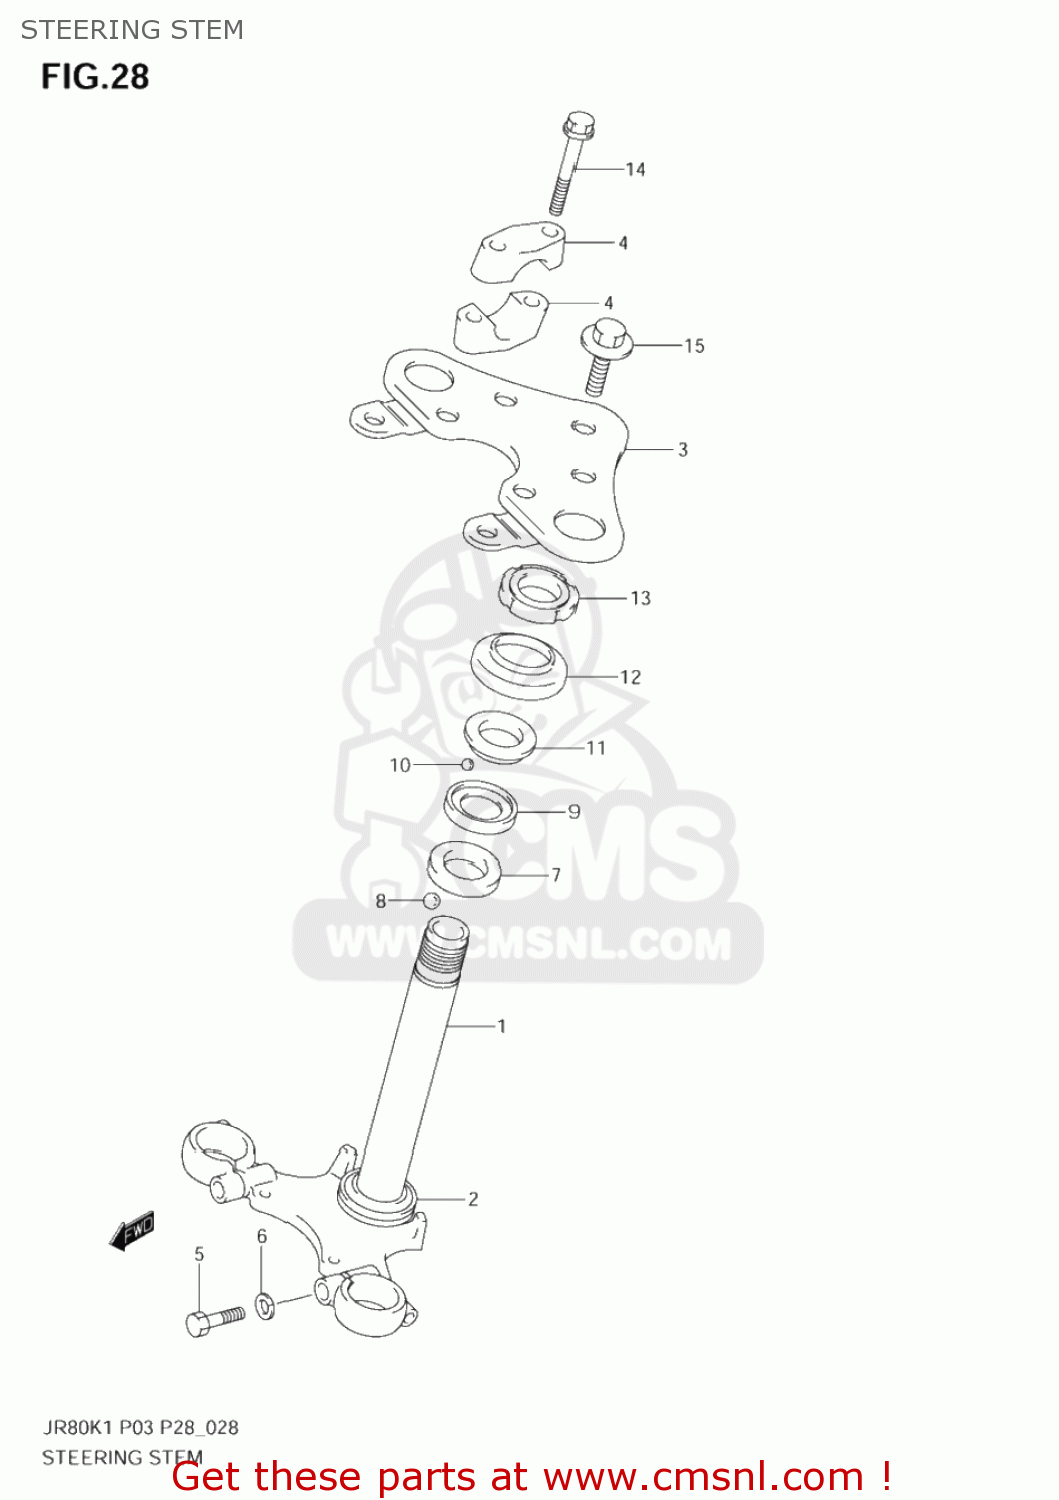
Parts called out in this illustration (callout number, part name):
1	STEM,STEERING
2	RACE,STEERING OUTER LWR
3	HEAD,STEERING STEM
4	HOLDER,HANDLE UPR
5	BOLT
6	WASHER,LOCK
7	LACE,STEERING INNER LWR
8	BALL
9	RACE,STEERING INNER UPR
10	BALL
11	RACE,STEERING OUTER UPR
12	DUST SEAL,STEERING UPR
13	NUT,STEERING STEM(25X44X10)
14	BOLT
15	BOLT
